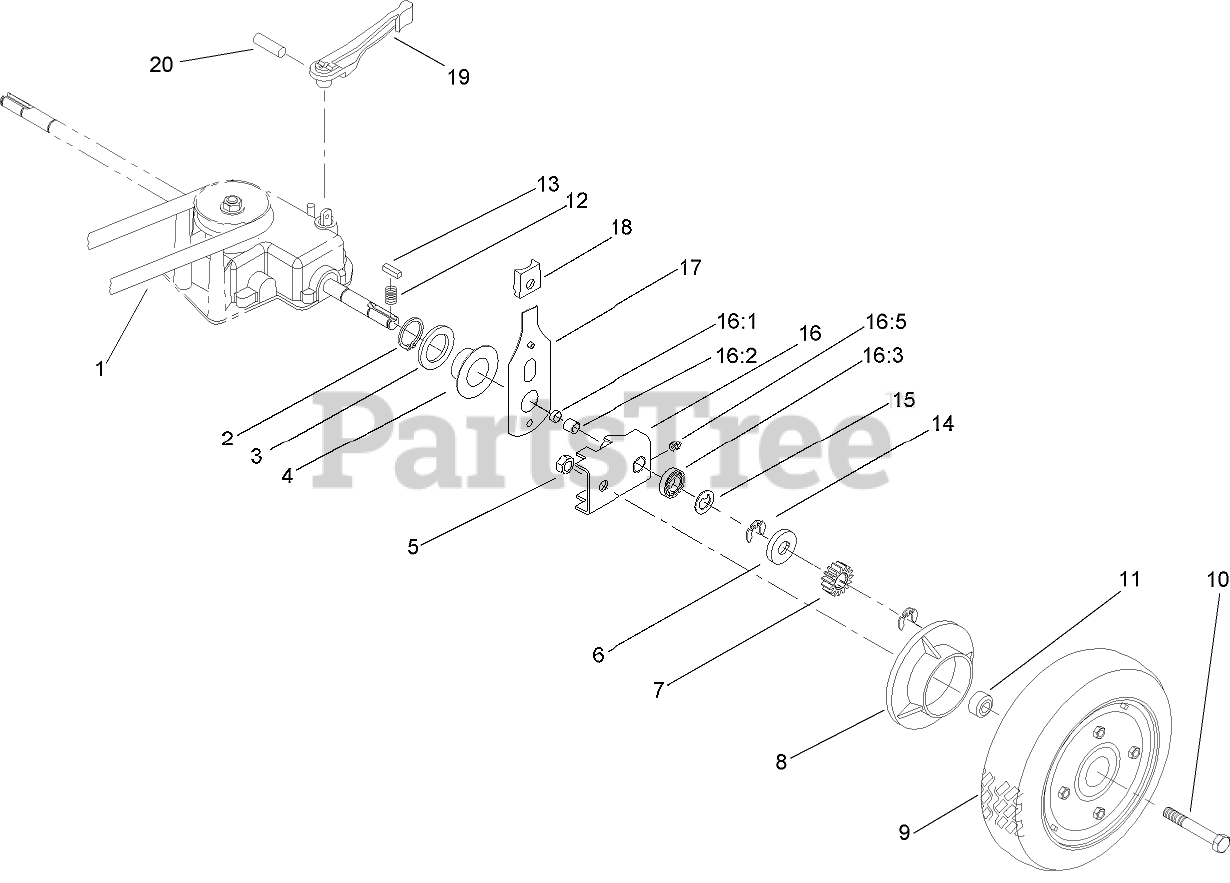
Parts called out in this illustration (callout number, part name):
1	V-BELT
2	RING-RETAINING
3	WASHER
4	CAP-END
5	NUT-LOCK, CONE
6	WASHER-THRUST, OUTER
7	GEAR-PINION
8	COVER-WHEEL
9	Wheel And Tire ASM
10	SCREW-HH
11	SPACER-COVER, WHEEL
12	SPRING-COMPRESSION
14	RING-RETAINING
15	WASHER-THRUST, OUTER
16	PIVOT ARM ASM
16:1	SEAL-OIL
16:2	BEARING-ROLLER
16:3	BEARING-WHEEL
17	REAR SPRING ARM ASM
18	KNOB-ARM
19	LEVER-SHIFT
20	PIN-COIL
